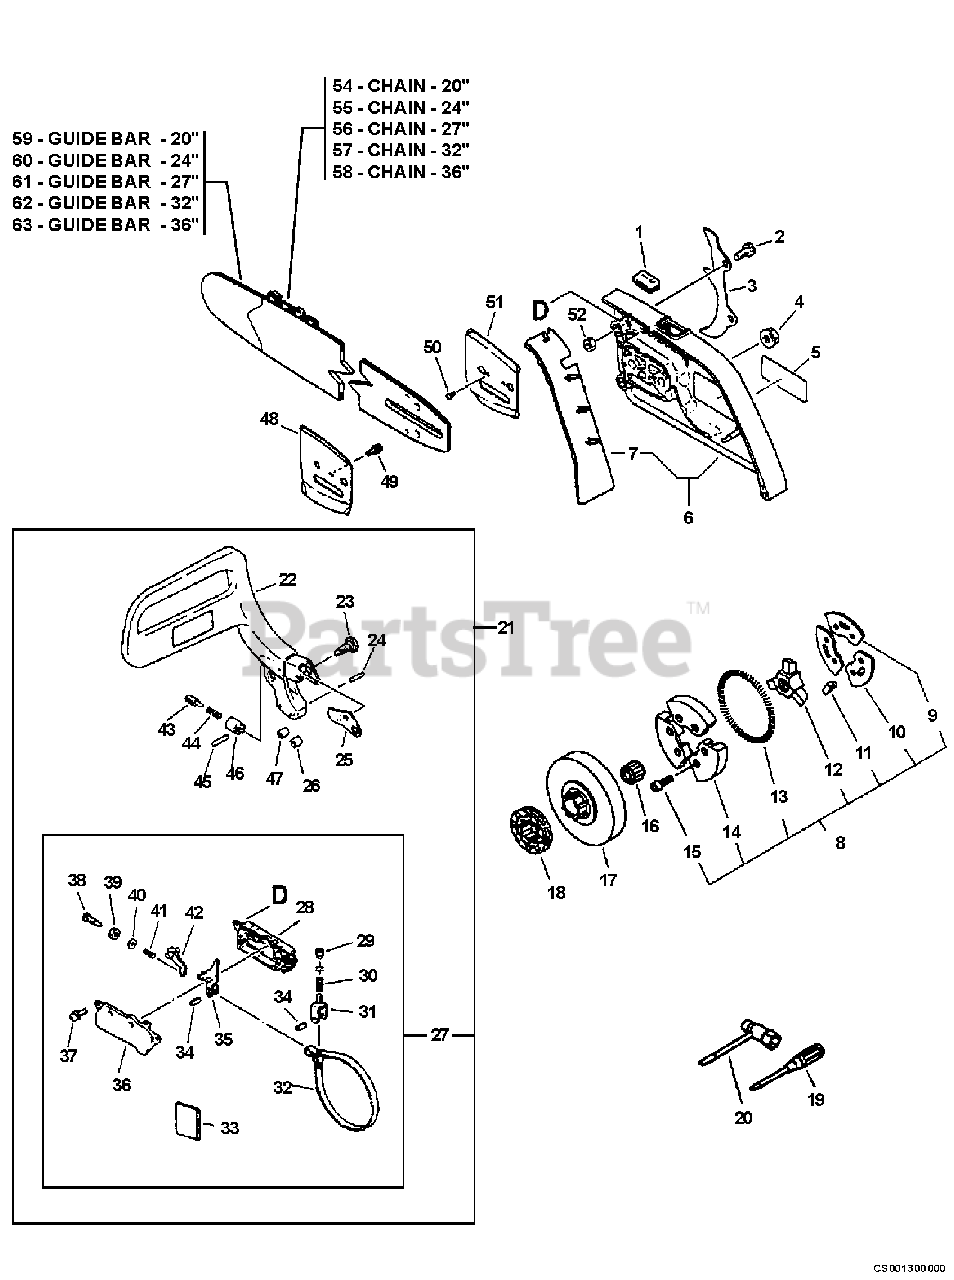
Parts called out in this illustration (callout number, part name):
4	NUT - FLANGE
5	LABEL - ECHO
6	GUARD, SPROCKET
8	CLUTCH ASSY
9	PLATE, CLUTCH
10	PLATE, CLUTCH
11	PLATE, SPRING
12	HUB, CLUTCH
13	SPRING, CLUTCH
14	CLUTCH SHOE SET
15	SCREW - 4X8
16	BEARING, NEEDLE
17	DRUM, CLUTCH
18	SPROCKET, RIM
19	SCREWDRIVER
20	T-WRENCH - 13X19mm
21	CHAIN BRAKE ASSY
22	LEVER, BRAKE
27	CHAIN BRAKE ASSY
28	COVER, BRAKE
31	ADJUSTER, BRAKE BAND
32	BAND, BRAKE
34	PIN - SPRING
35	LEVER, BRAKE
36	COVER, BRAKE
37	SCREW - 4X10
41	SPRING, BRAKE
42	STOPPER, BRAKE
47	SPACER
48	PLATE, GUIDE - INNER
49	SCREW - 4X8
50	SCREW - 3X6
51	PLATE, GUIDE - OUTER
54	SAW CHAIN - 20" (50cm)
55	SAW CHAIN - 24" (60cm)
56	SAW CHAIN - 27" (68cm)
57	SAW CHAIN - 32" (81cm)
58	SAW CHAIN - 36" (91cm)
59	GUIDE BAR - 20" (50cm)
60	GUIDE BAR - 24" (60cm)
61	GUIDE BAR - 27" (68cm)
62	GUIDE BAR - 32" (81cm)
63	GUIDE BAR - 36" (91cm)
